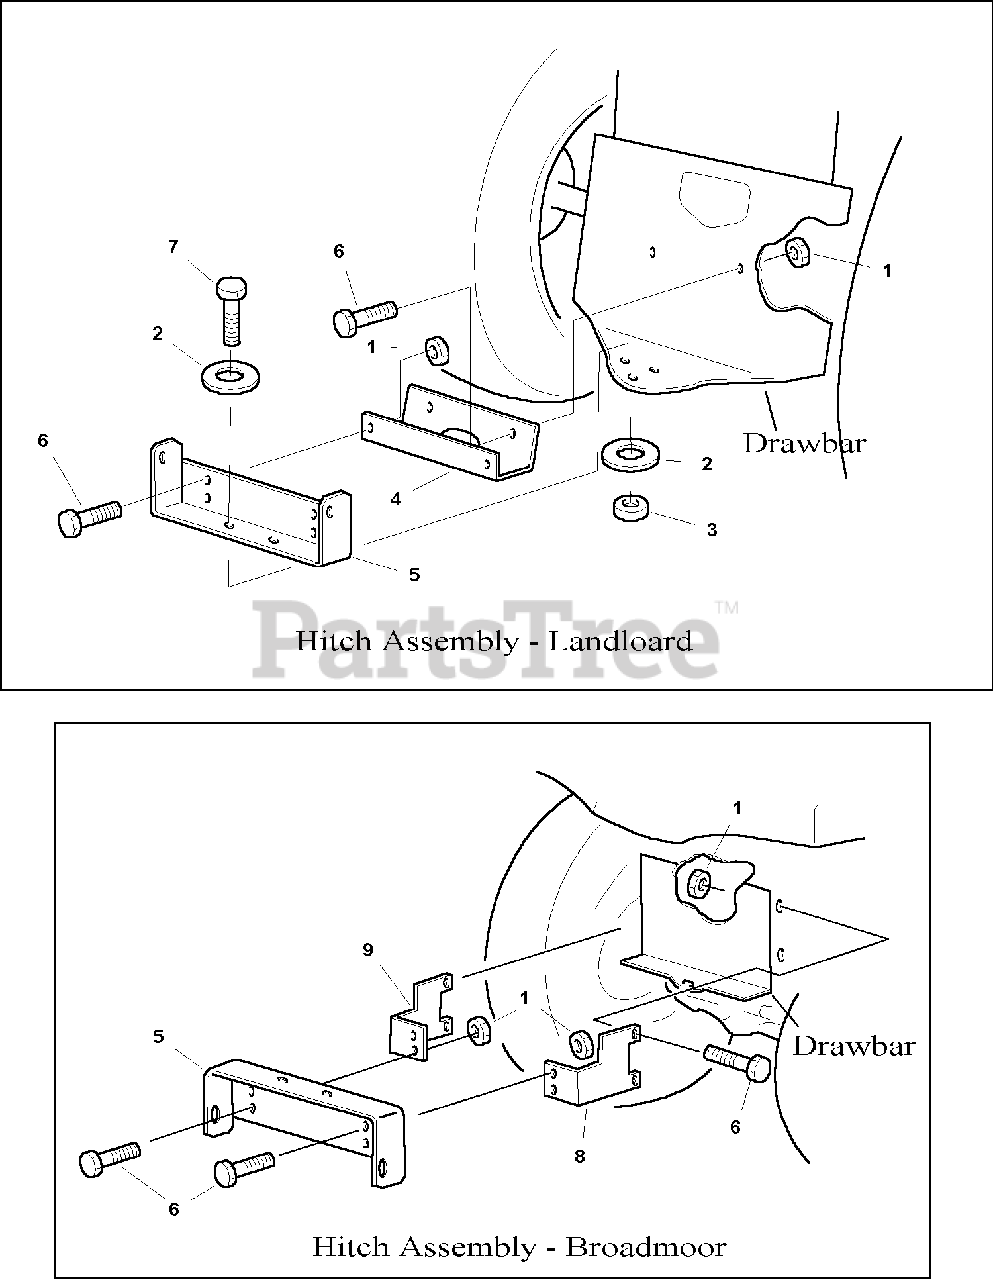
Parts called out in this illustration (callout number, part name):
1	LOCKNUT, Hex Flange, 3/8-16 (quanity 4 used for Landlord)
2	WASHER
3	LOCKNUT, Hex, 1/2
4	HITCH, Support
5	HITCH
6	CAPSCREW, Hex Head, 3/8/-16 x 1 (quanity 4 used for Landlord)
7	CAPSCREW, Hex Head, 1/2-13 x 1-1/4
8	HITCH ADAPTER, R. H.
9	HITCH ADAPTER, L. H.
